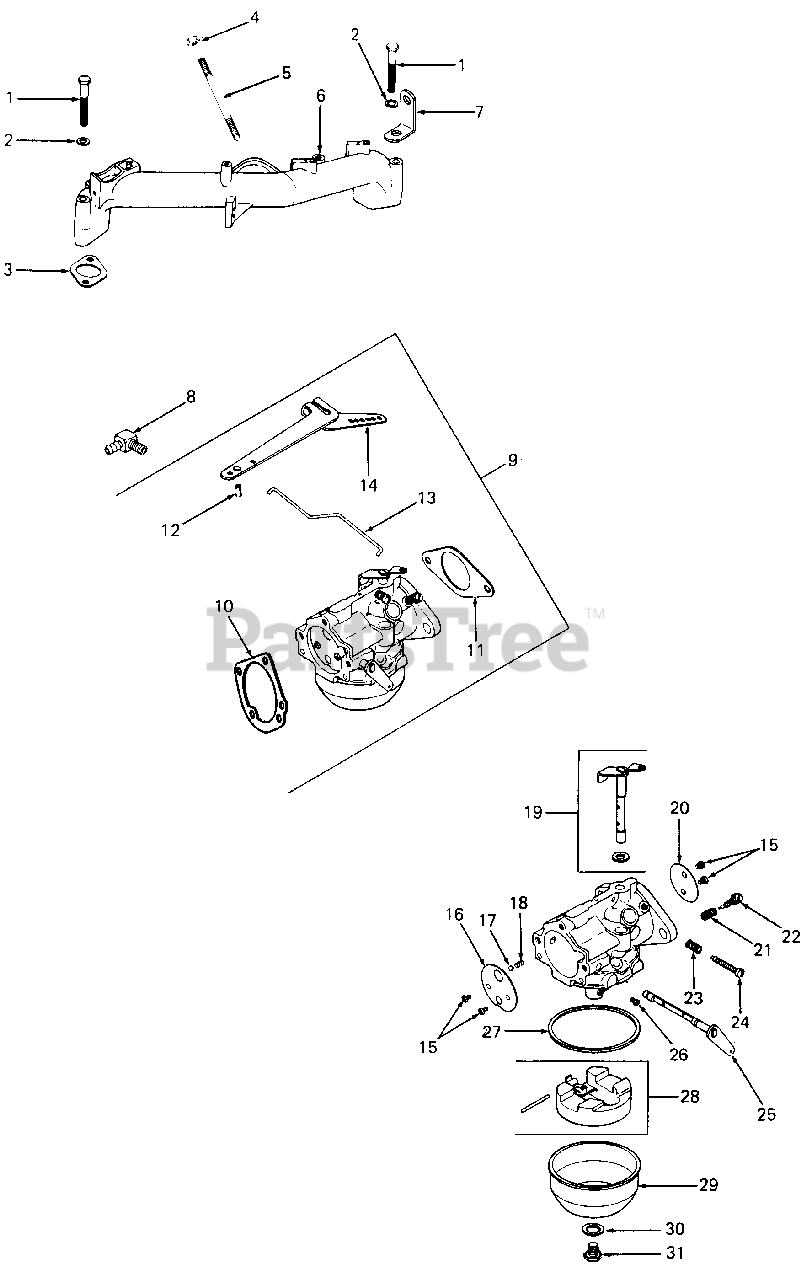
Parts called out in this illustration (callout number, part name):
1	Screw, H.C., 5/16-18 X 2.75 Lg
2	Washer, Lock, 5/16
3	Gasket, Intake Manifold
4	Nut, Hex Jam, 5/16-18
5	Stud, 5/16-18 X 1.0 Lg
6	Manifold, Intake
7	Strap, Lifting
8	Connector, 90
9	Kit, Carburetor w/Linkage
10	Gasket, Elbow
11	Gasket, Carburetor
12	Bushing, Linkage Retaining
13	Linkage, Governor
14	Arm, Governor
15	Screw, Throttle & Choke Plate
16	Plate, Choke
17	Ball, Choke Friction
18	Spring, Choke Friction
19	Shaft, Throttle w/Lever & Seal
20	Plate, Throttle
21	Spring, Idle Fuel
22	Needle, Idle Fuel Adj
23	Spring, Idle Speed
24	Screw, Idle Speed Adj
25	Lever, Choke
27	Gasket, Bowl
30	Gasket, Bowl Retainer Screw
31	Screw, Bowl Retainer
